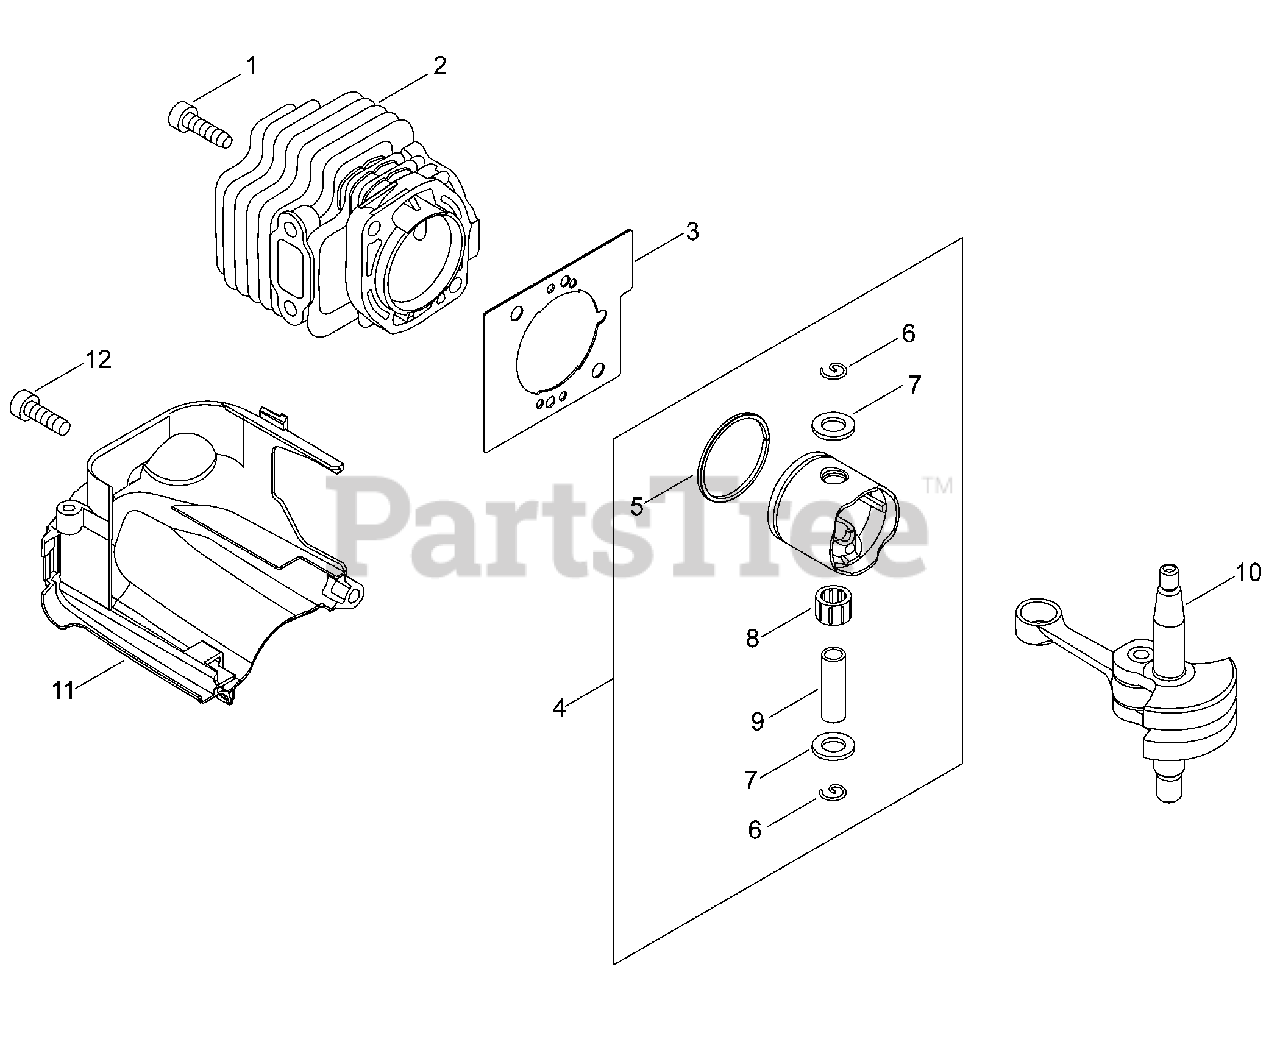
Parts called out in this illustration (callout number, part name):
1	BOLT, TORX 5
2	CYLINDER
3	GASKET,CYL
4	PISTON KIT
5	RING,PISTON
6	CIRCLIP, PISTON PIN
7	SPACER, PISTON PIN
8	BEARING, NEEDLE
9	PIN,ENG 8
10	CRANKSHAFT,ASY
11	COVER,CYLINDER
12	BOLT, TORX 5
